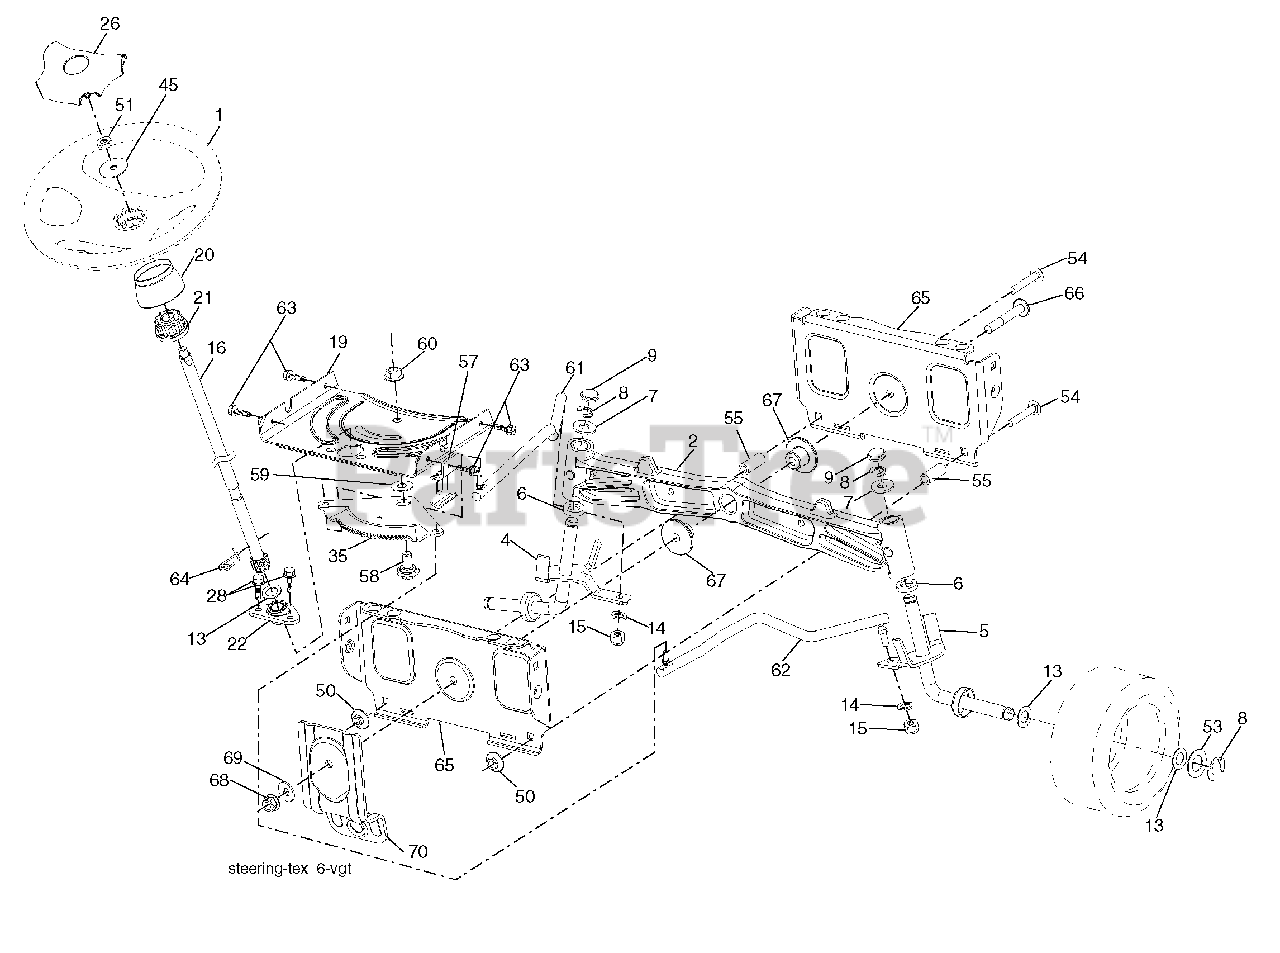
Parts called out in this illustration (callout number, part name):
1	Wheel, Steering
2	Axle Asm., Front
4	Spindle Asm., LH
5	Spindle Asm., RH
6	Bearing, Race Thrust Harden
7	Washer 25/32 x 1-5/8 x 16 Ga.
8	Ring, Klip #T5304-75
9	Cap, Spindle
13	Washer 25/32 x 1-1/4 x 16 Ga.
14	Washer, Lock Hvy Hlcl Spr 3/8
15	Nut, Crown Lock 3/8-24 unf
16	Shaft Steering
19	Plate Steering
20	Boot, Steering
21	Adapter, Wheel Steering
22	Bushing, Strg. Blk
26	Insert, Wheel Steering
28	Screw 3/8-16 x 3/4
35	Gear, Sector Plate
45	Washer 11/32 x 2-3/8 x 12 Ga.
50	Nut Lock 3/8-16 UNC
51	Nut Hex Jam Toplock 1/2-20 unf
53	Washer Hardened .793 x 1.637 x .060
54	Bolt Hex 3/8-16 UNC x 2-1/4
55	Spacer Brace Axle
57	Bracket Upstop
58	Bolt Shoulder Sector Pivot CFM
59	Washer Thrust Sector Steering
60	Nut Flange Lock 5/8-11
61	Draglink LH
62	Draglink, RH
63	Screw 5/16-18 x 3/4
64	Retainer Clip Spring Steering
65	Brace Axle Front
66	Bolt Hex Fghd 7/16-14 x 3 Serr
67	Bushing PM Front Axle
68	Nut Lock Flange 7/16-14 Gr. 5
69	Washer 1.5 x .505 x .118
70	Bracket Deck Susp. Front
